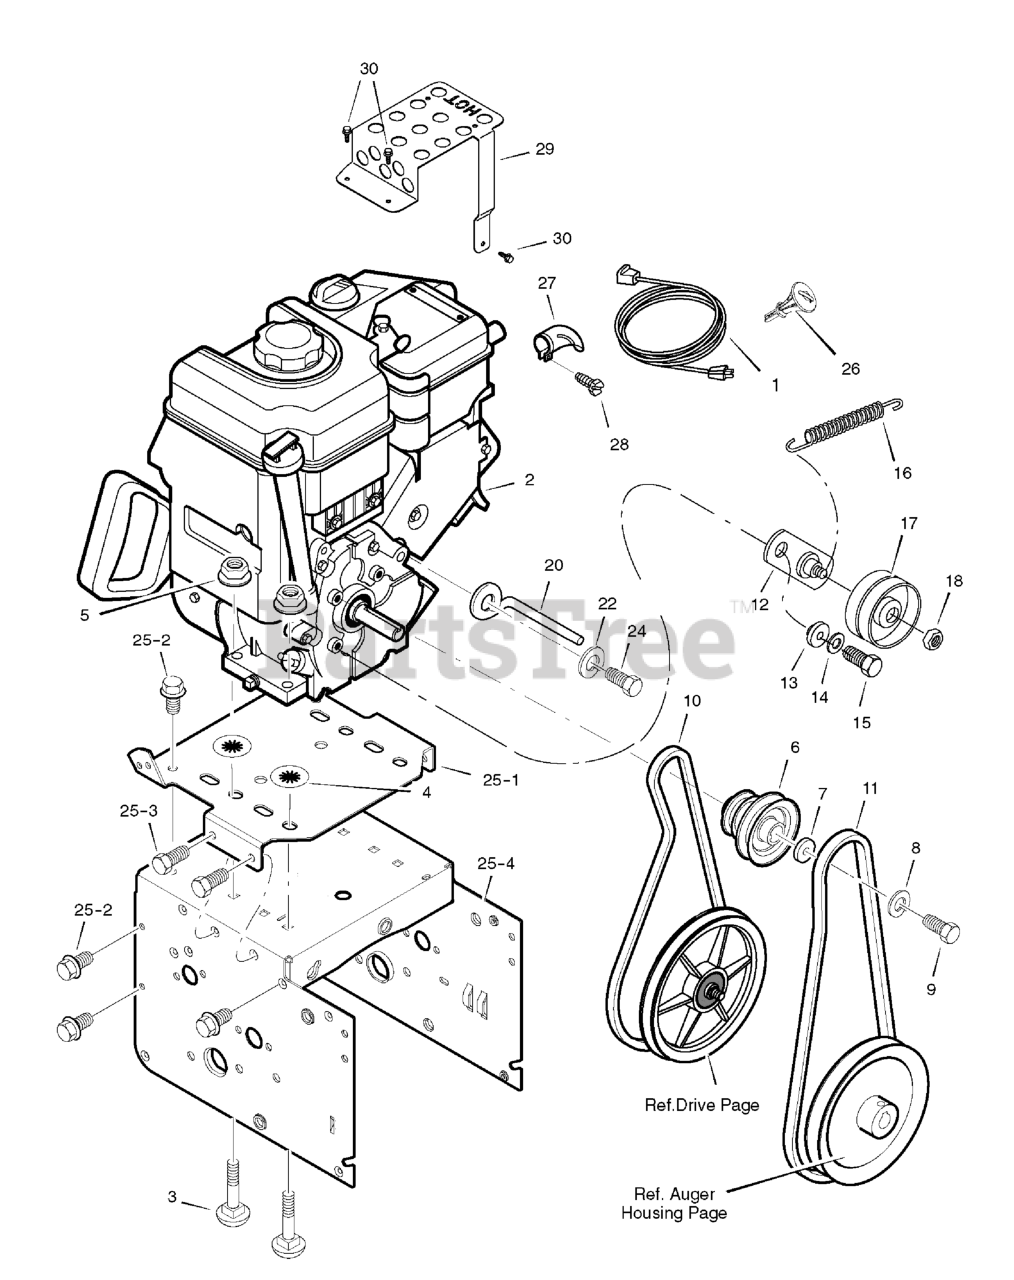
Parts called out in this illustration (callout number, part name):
1	CORD, Starter
2	ENGINE
3	BOLT, Carriage
4	RETAINER, Push
5	NUT
6	PULLEY, Engine
7	WASHER
8	WASHER, Flat
9	BOLT, Hex 5/16-24 x 1
10	BELT, Drive V, 4L
11	BELT, Auger V, 3L
12	BRACKET ASSEMBLY, Idler
13	BUSHING, Idler Bracket
14	WASHER, Split
15	SCREW 5/16 - 24 x 3/4
16	SPRING, Idler Traction Drive
17	PULLEY, Idler
18	NUT, Jam 3/8 - 16
20	GUIDE, Rod Belt
22	WASHER
24	SCREW
25	FRAME ASSEMBLY
25-1	PLATE, Engine
25-2	SCREW
25-3	SCREW
25-4	MOTOR BOX
26	KEY, Briggs Engine
27	DEFLECTOR, Muffler
29	HEAT SHIELD, Muffler
